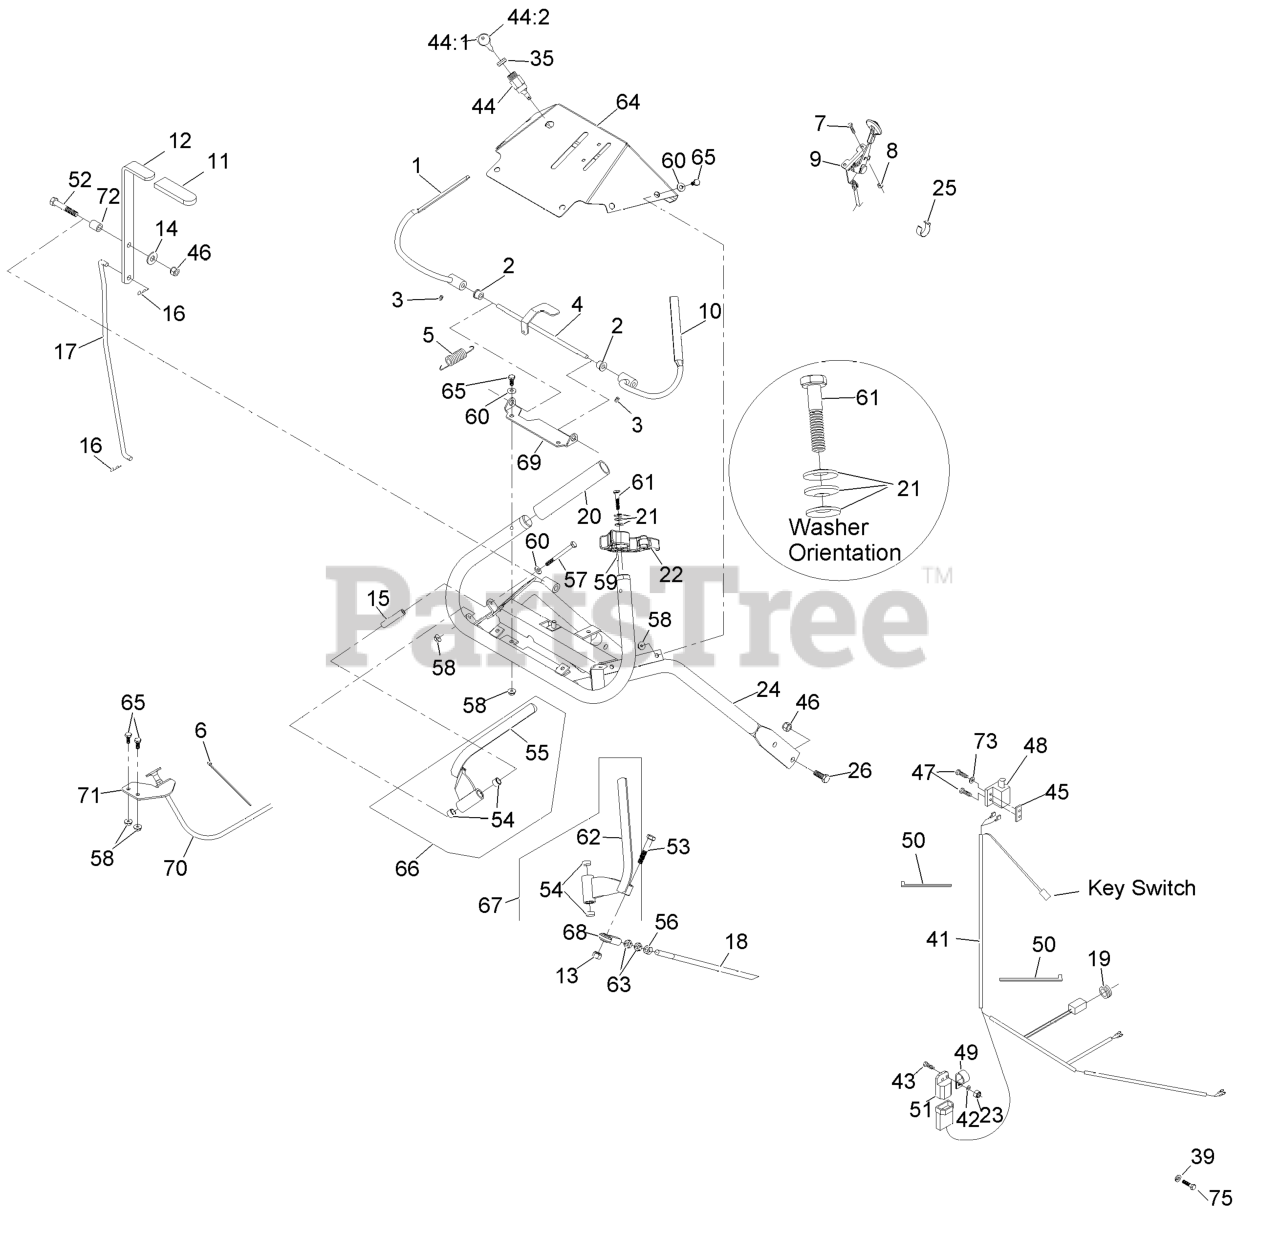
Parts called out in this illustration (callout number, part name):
1	WLD,LH OPC LEVER
2	BUSHING-NYLON
3	SCREW-SET
4	WLD,OPC LEVER AXLE
5	SPRING-EXTENSION
6	TIE-PLASTIC
7	BOLT-CARR
8	NUT-LOCK, NI
9	CONTROL, THROTTLE
10	WLD,RH OPC LEVER
11	GRIP-LEVER
12	CLUTCH LEVER-W/GRIP
13	NUT-LOCK, NI
14	WASHER-FLAT
15	BUSHING-LEVER, DRIVE
16	PIN-COTTER
17	LINKAGE,UPPER BLADE (PLT)
18	LINKAGE,DRIVE (PLT)
19	GROMMET
20	GRIP-BAR, HANDLE
21	WASHER-SPRING
22	ASM,RH THUMB LATCH
23	NUT-LOCK, NI
24	WLD,UPPER ECS HANDLE
25	CLIP-CABLE
26	SCREW-HH
35	NUT-SWITCH, IGNITION
39	WASHER-PLAIN
41	HARNESS-WIRE
42	WASHER-FLAT
43	SCREW-HH
44	SWITCH & KEY (INCLUDES NU
44:1	KEYS-IGNITION (SPARE PAIR
44:2	KEY-IGNITION
45	PLATE-TAPPED
46	NUT-LOCK, NI
47	SCREW-PPH
48	SWITCH-OPEN, NORMALLY
49	CLIP-LOOM
50	TIE-CABLE
51	MODULE-INTERLOCK
52	SCREW-CARR
53	SCREW-HH
54	BUSHING-SLEEVE
55	WLD,LH DRIVE LEVER
56	NUT-HEX
57	SCREW-HH
60	WASHER-FLAT
61	SCREW-HH
62	WLD,RH DRIVE LEVER
63	NUT-HJ
64	ASM, CONSOLE W/DECALS
65	SCREW-HH
66	DRIVE LEVER-ASM, RH
67	DRIVE LEVER-ASM, LH
68	JOINT-BALL, END
69	BRACKET,OPC AXLE
70	CABLE-CHOKE
71	BRACKET-CABLE, CHOKE
72	BUSHING-LEVER, LIFT
73	WASHER-FLAT
75	SCREW-HH
